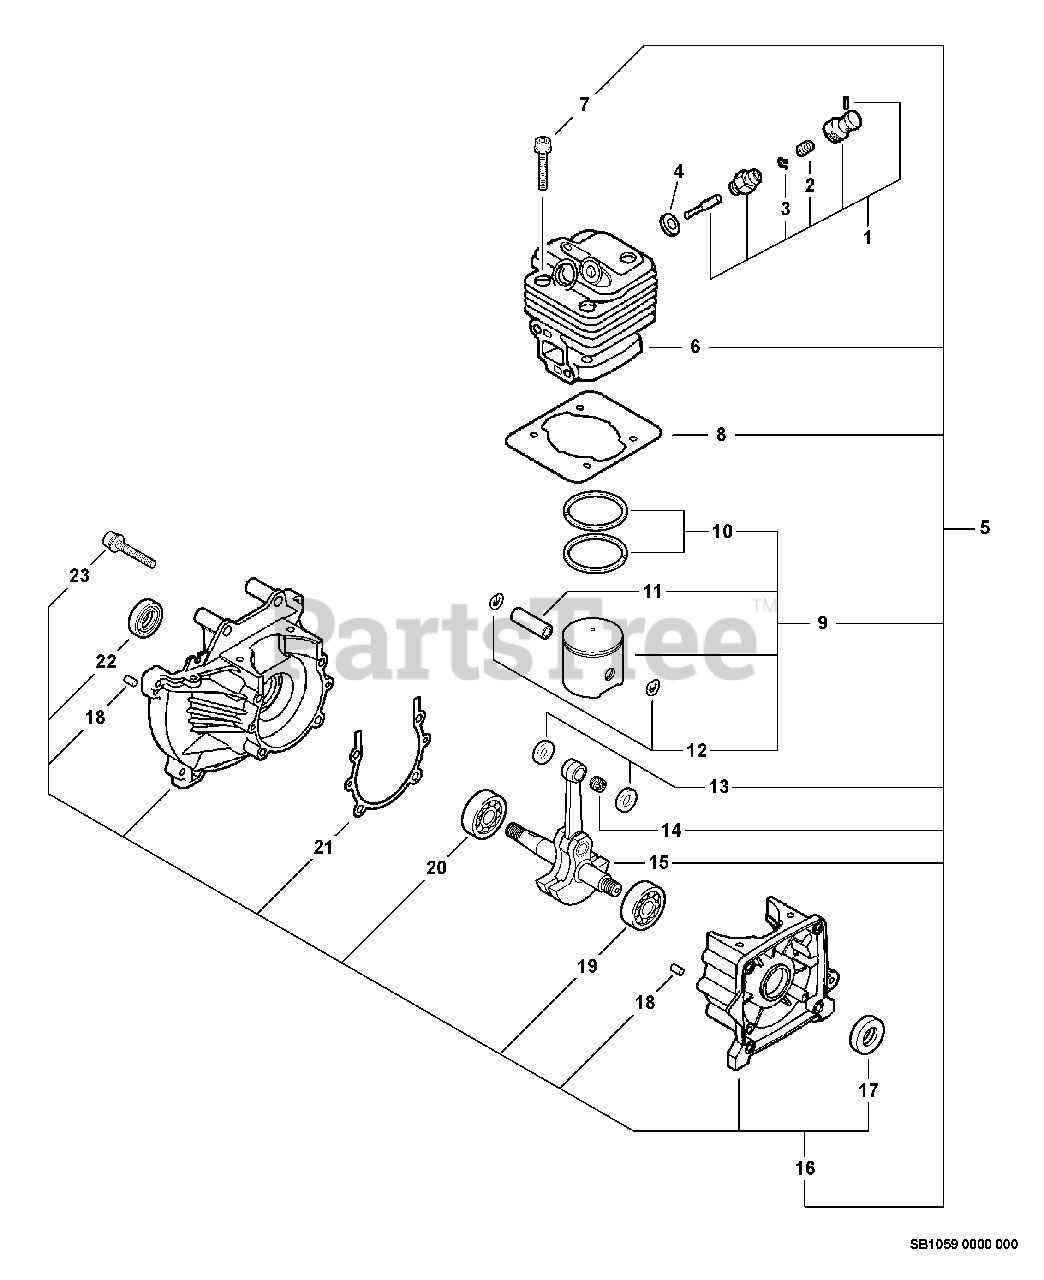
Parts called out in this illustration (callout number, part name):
1	VALVE, DECOMPRESSION
4	GASKET
5	SHORT BLOCK
6	CYLINDER
7	BOLT 5×20
8	GASKET, CYLINDER
9	PISTON KIT
10	RING, PISTON
11	PIN, PISTON 10
12	RING, SNAP 8
13	WASHER, THRUST
14	BEARING, NEEDLE 10
15	CRANKSHAFT ASSY
16	CRANKCASE KIT
17	SEAL, OIL 12
18	PIN, LOCATING 4
19	BEARING, BALL - 6201 C3
20	BEARING, BALL 6202
21	GASKET, CRANKCASE
22	SEAL, OIL
23	BOLT M5×35
